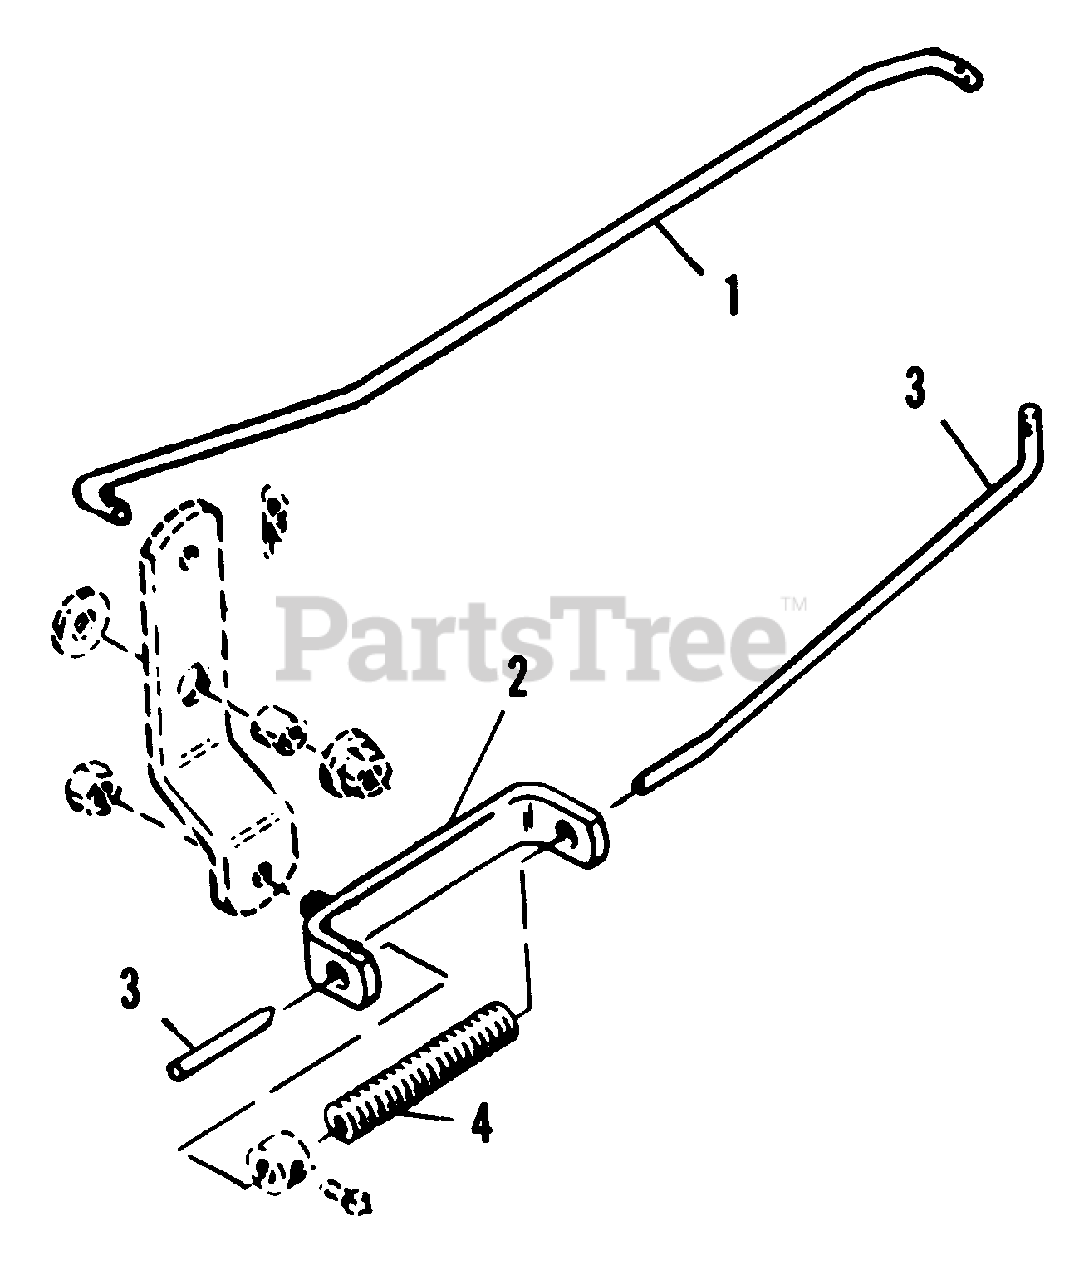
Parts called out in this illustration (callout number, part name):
1	ROD, P.T.O.
1	ROD, P.T.O. (42"-6111)
2	ROD GUIDE ASSY.
3	ROD, Clutch
